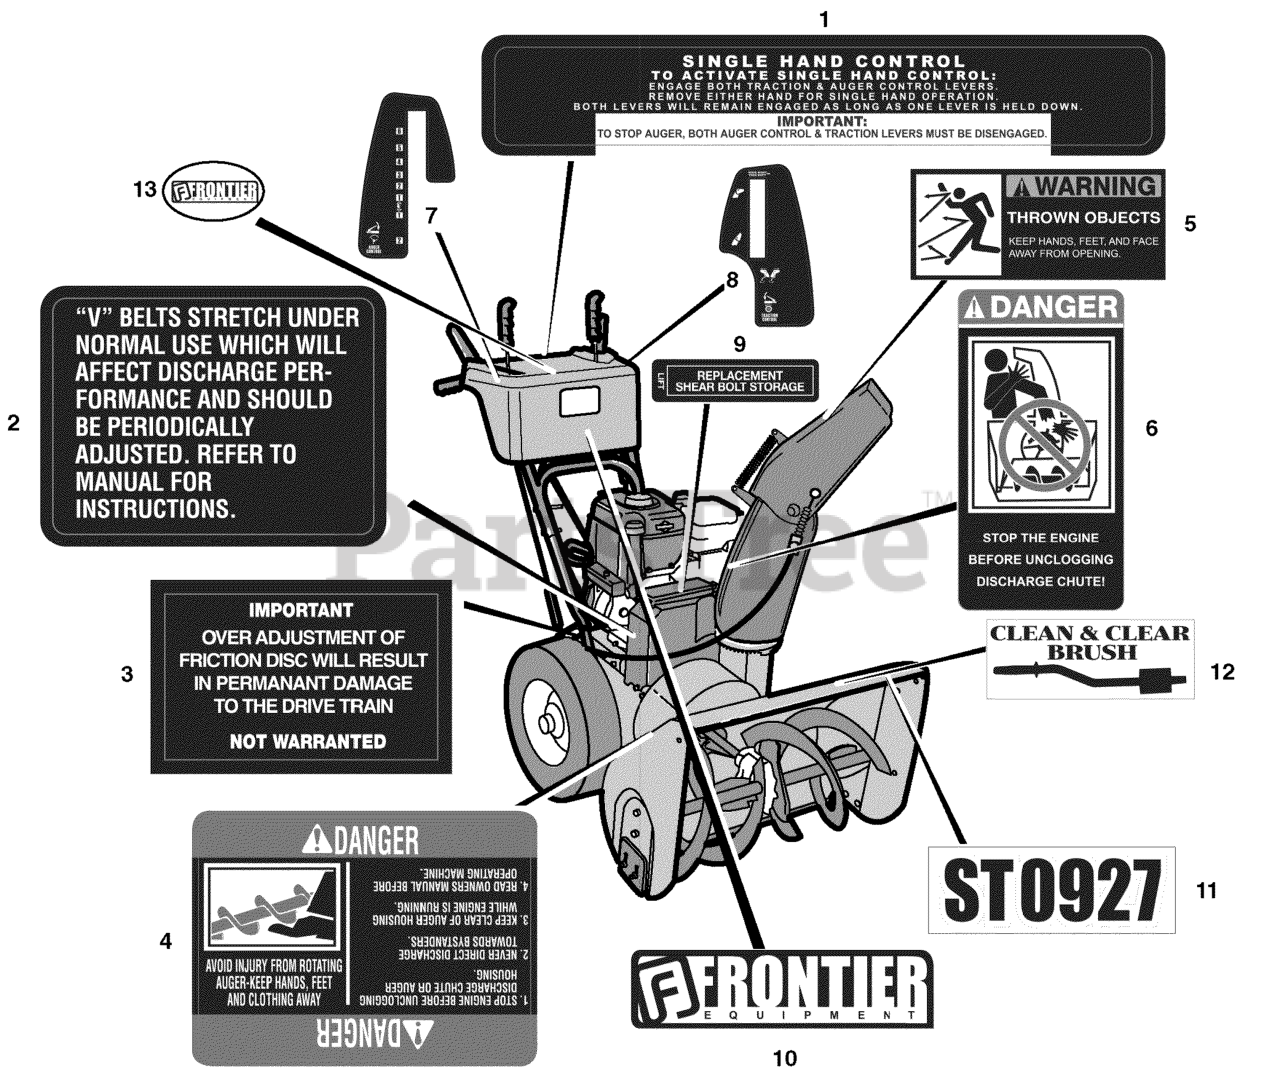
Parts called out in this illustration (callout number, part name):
1	DECAL, SINGLE HAND CONTROL
2	DECAL, V-BELTS
3	DECAL, OVER ADJUSTMENT
4	DECAL, ROTATING AUGER
5	DECAL, DANGER
6	DECAL, UNCLOGGING CHUTE
7	DECAL, SPEED CONTROL
8	DECAL, REMOTE CHUTE CONTROL
9	DECAL, SHEAR BOLTS
10	LOGO NAMEPLATE, FRONTIER
11	DECAL, ST0927
12	DECAL, CLEAN & CLEAR BRUSH
13	DECAL, PANEL
